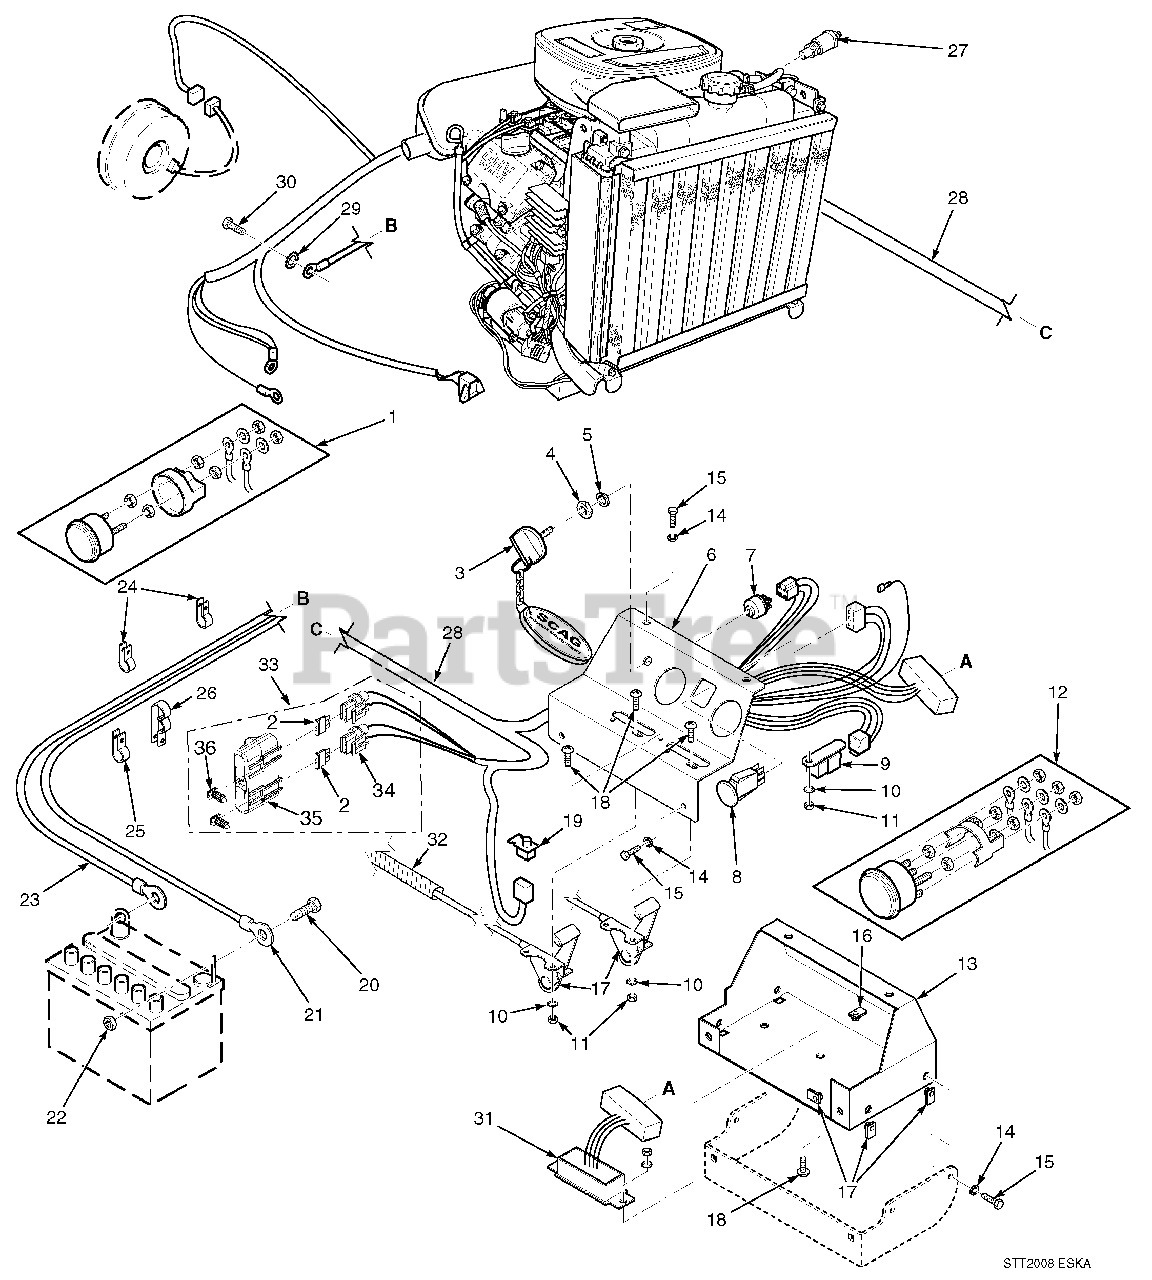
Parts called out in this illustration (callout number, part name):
1	Ammeter
2	Fuse, 20 AMP
3	Key, Ignition
4	Nut, Hex 5/8-32
5	Lockwasher, 5/8" Internal
6	Instrument Panel, Top w/Decals
7	Key Switch
8	Switch, PTO
9	Relay
10	Lockwasher, #10 External Tooth
11	Nut, Hex #10-32
12	Water Temp. Gauge
13	Base, Instrument Panel
14	Lockwasher, 1/4"
15	Bolt, Hex Head 1/4-20 x 3/4"
16	U-Nut, 1/4-20
17	Throttle And Choke Controls
18	Screw, Phillips Washer Head #10-32 x 1/2"
19	Switch, Interlock-Seat
20	Bolt, Hex Head 1/4-20 x 1/2"
21	Cable, Battery - Red
22	Nut, Hex 1/4-20
23	Cable, Battery - Black
24	Clamp, Cable 1/2" ID.
25	Clamp, Cable 3/4" ID.
26	Clamp, Cable
27	Sending Unit, Water Temp.
28	Wire Harness, STT Kawasaki Liquid-Cooled
29	Lockwasher, 5/16" External Tooth
30	Bolt, Hex Head M8-1.25 x 20mm
31	Electronic Module
32	Heatshield, Flexible
33	Double Fuse Assembly, Sealed
34	Fuse Holder
35	Cover, Sealed Double
36	Clip, Wire
